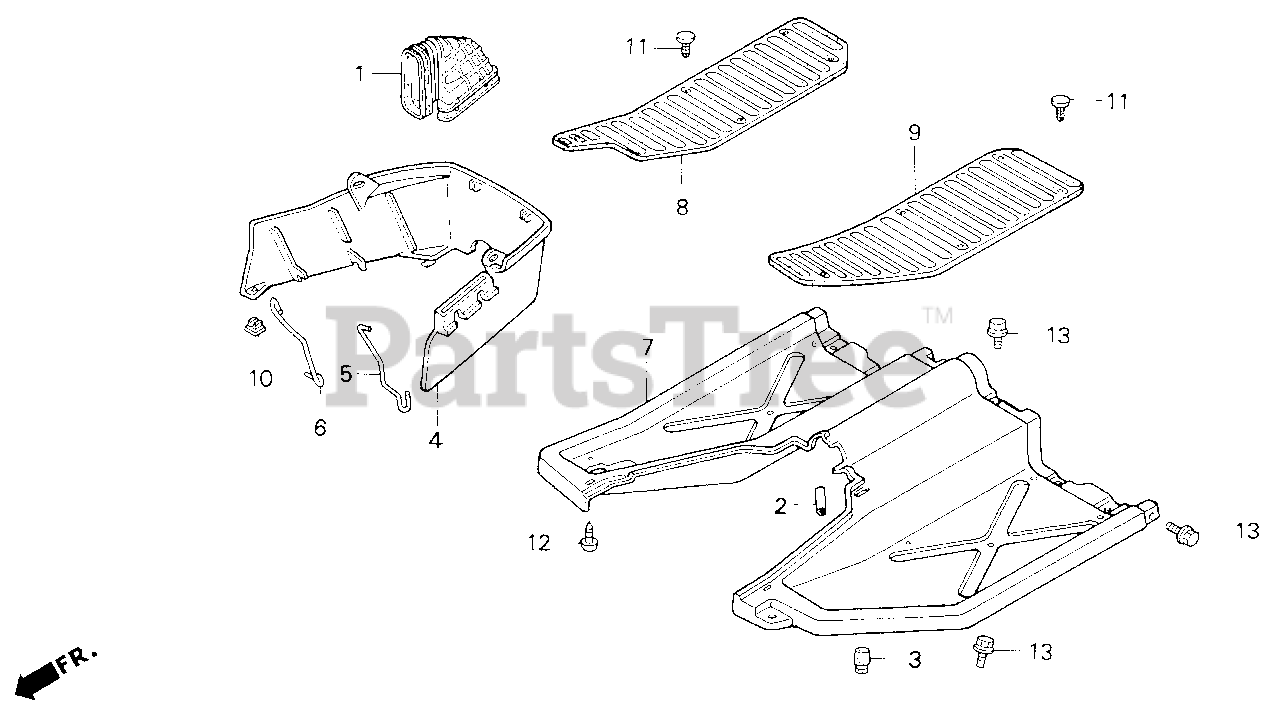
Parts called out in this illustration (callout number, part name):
3	RUBBER A, STOPPER
4	SHELL, COMPARTMENT *R165* (JOLLY RED)
5	ROD, COMPARTMENT SHELL
6	ROD, R. COMPARTMENT SHELL
7	PANEL, FLOOR *R165* (JOLLY RED)
8	FLOOR MAT, R.
9	FLOOR MAT, L.
10	GROMMET, SCREW (6MM)
11	CLIP, TRIM (5MM) *NH1L* (BLACK)
12	SCREW, TAPPING (5X16)
13	BOLT, FLANGE (6X12)
